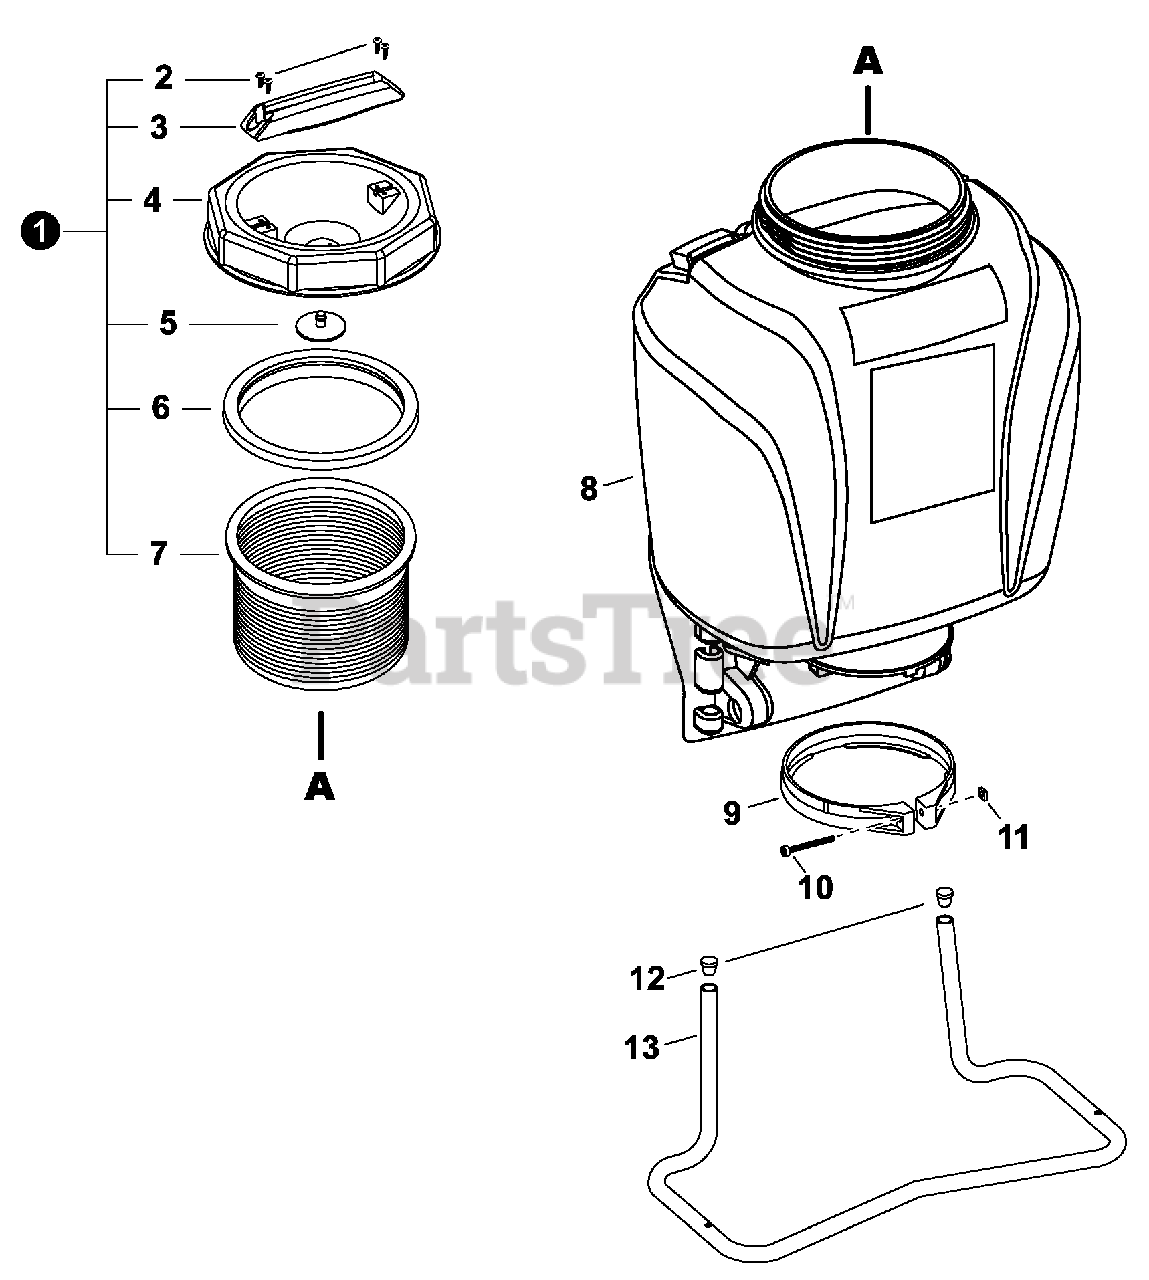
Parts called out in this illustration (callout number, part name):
1	CAP KIT, TANK
2	SCREW
3	HANDLE
4	CAP, TANK
5	VALVE, CHECK - CAP
6	GASKET, BASKET
7	BASKET, FILTER
8	TANK, SPRAYER
9	CLAMP, PUMP
10	SCREW, CLAMP
12	CAP, BASE
13	BASE, TANK
